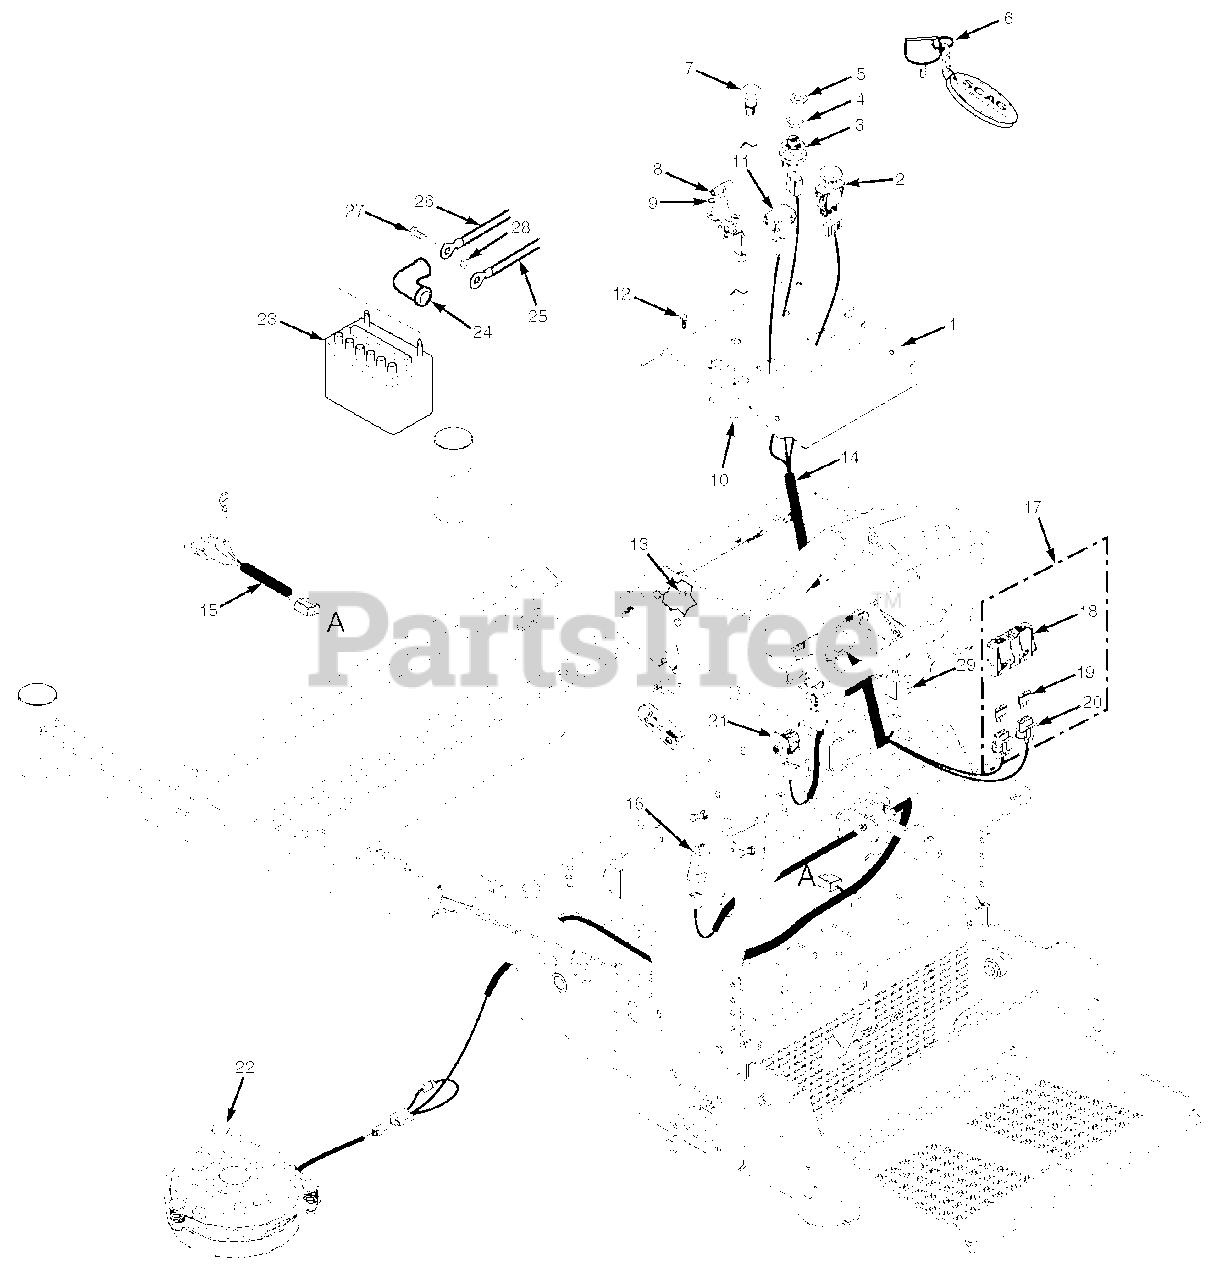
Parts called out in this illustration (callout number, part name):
1	Instrument Panel w/Decal
2	Switch, PTO - 10 Amp
3	Key Switch
4	Lockwasher, 5/8" Internal Tooth
5	Nut, 5/8-32 Special
6	Key Chain w/ Keys
6	Key w/Shroud
7	Choke Control, SVR
8	Throttle Control, SVR
9	Bolt, Carriage #10-24 x 1/2"
10	Locknut, #10-24
11	Hourmeter
12	Bolt, Hex Head 1/4-20 x .63
13	Nut, Serrated Flange 1/4-20
14	Wire Harness, SVR
15	Wire Harness Adapter, Kawasaki
16	Switch, Interlock
17	Double Fuse Assy.
18	Cover, Sealed Double
19	Fuse, 20 Amp
20	Fuse Holder
21	Switch, Double Pole - Plunger
22	Clutch w/Tag (36A, 48V, 52V)
22	Clutch w/Tag (61V)
23	Battery (not avail. through Scag)
24	Rubber Boot
25	Cable, Battery Black 18"
26	Cable, Battery Red 18"
27	Bolt, Hex Head 1/4-20 x 3/4"
28	Nut, 1/4-20
29	Switch, Interlock
